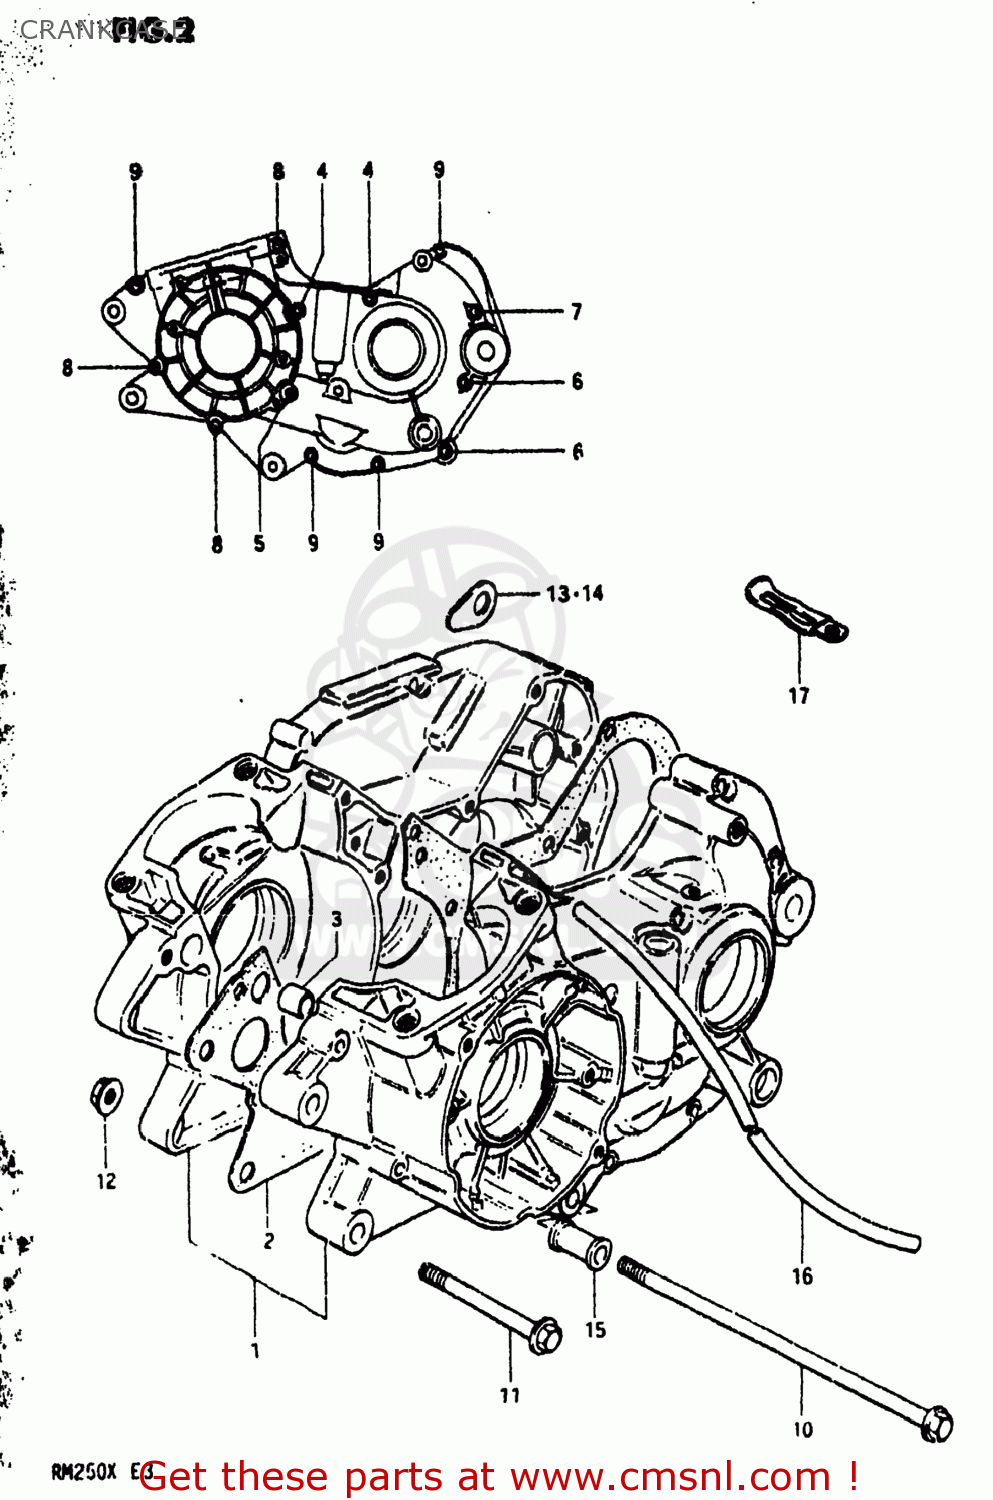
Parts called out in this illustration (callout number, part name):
1	CRANKCASE SET
2	GASKET,CRANKCASE (MCA)
3	PIN
4	SCREW 6X70
5	SCREW 6X60
6	SCREW
7	SCREW
8	SCREW (6X45)
9	SCREW (6X35)
10	BOLT
11	BOLT(8X75)
12	NUT
13	WASHER
14	WASHER
15	SPACER,ENGINE MOUNT
16	HOSE
17	CLAMP
